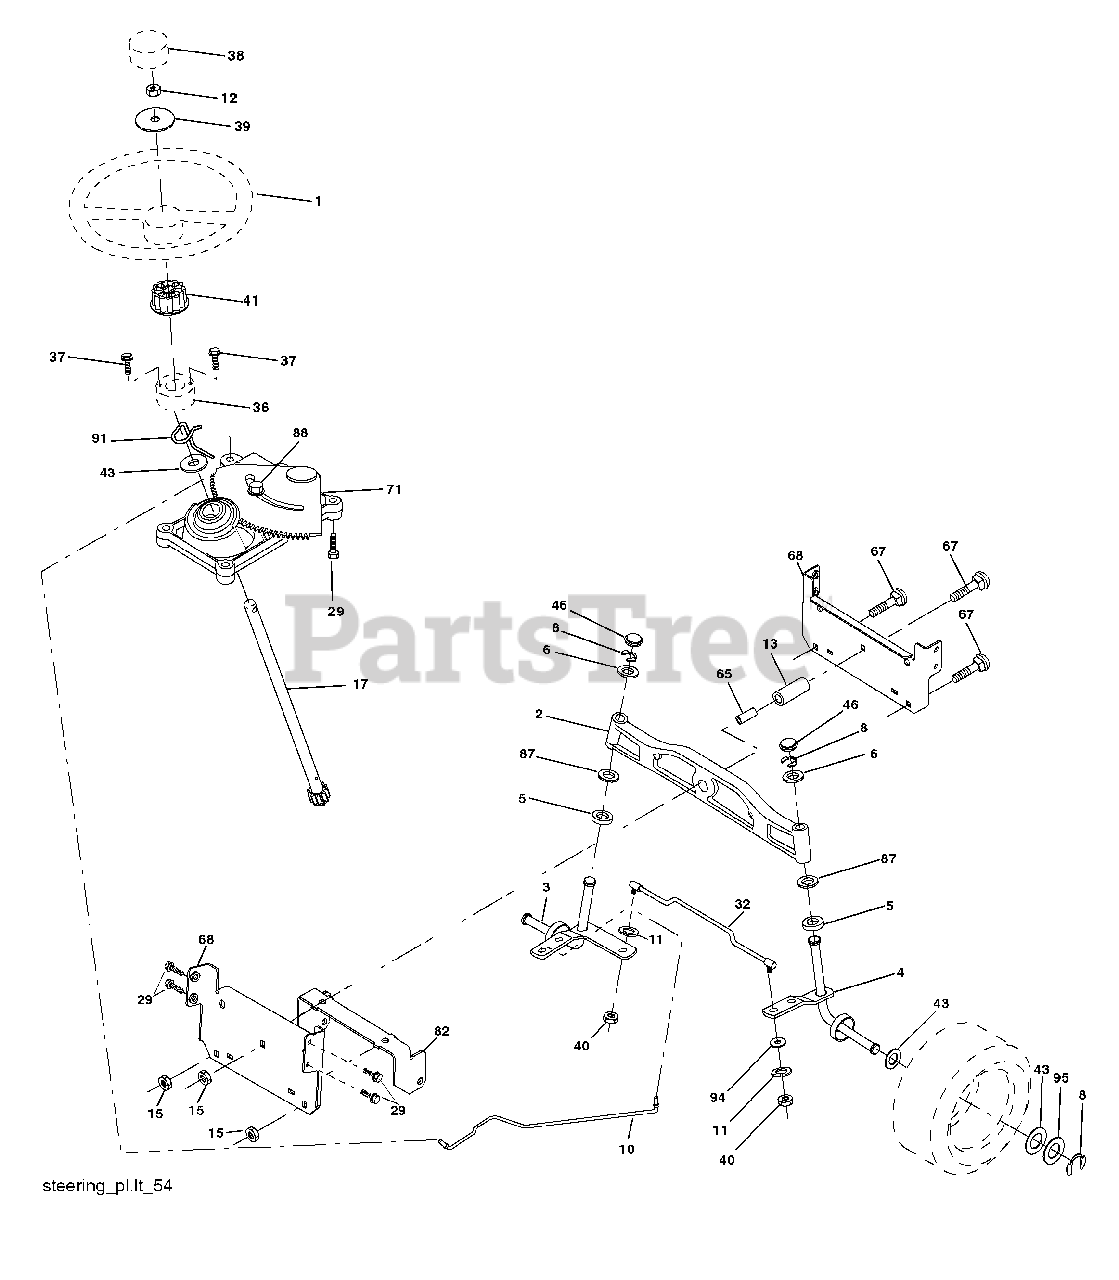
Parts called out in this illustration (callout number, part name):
1	Wheel Steering
2	Axle
3	Spindle Asm LH
4	Spindle Asm RH
5	Bearing Race Thrust Harden
6	Washer 25/32 x 1-5/8 x 16 Ga.
8	Ring Klip #t5304-75
11	Washer Lock Hvy Hlcl Spr 3/8
12	Nut Hex Jam Toplock 1/2-20 unf
13	Spacer Brg Axle Front
15	Nut Hex Flange Lock
17	Shaft Asm Strg
29	Screw 3/8-16 x 3/4
34	Washer Lock Hvy Helical 5/16
36	Bushing Strg
38	Insert Cap Strg Wh
39	Washer 9/16 x 2-3/8 12 Ga.
40	Nut Crownlock 3/8-24
41	Adaptor Wheel Strg
43	Washer 25/32 x 1 1/4 x 16 Ga.
46	Cap Spindle Fr Top Blk
65	Spacer Brace Axle
67	Bolt Rdhd Sq 3/8-16 x 2-1/4
68	Axle, Brace
71	Steering Asm
82	Bracket Susp Chassis Front
87	Washer Flat .781 x 1-1/2 x .14
88	Bolt Shoulder 7/16-20
91	Clip Steering
94	Washer 3/8 x 7/8 x 14 Ga.
95	Washer Hardened
